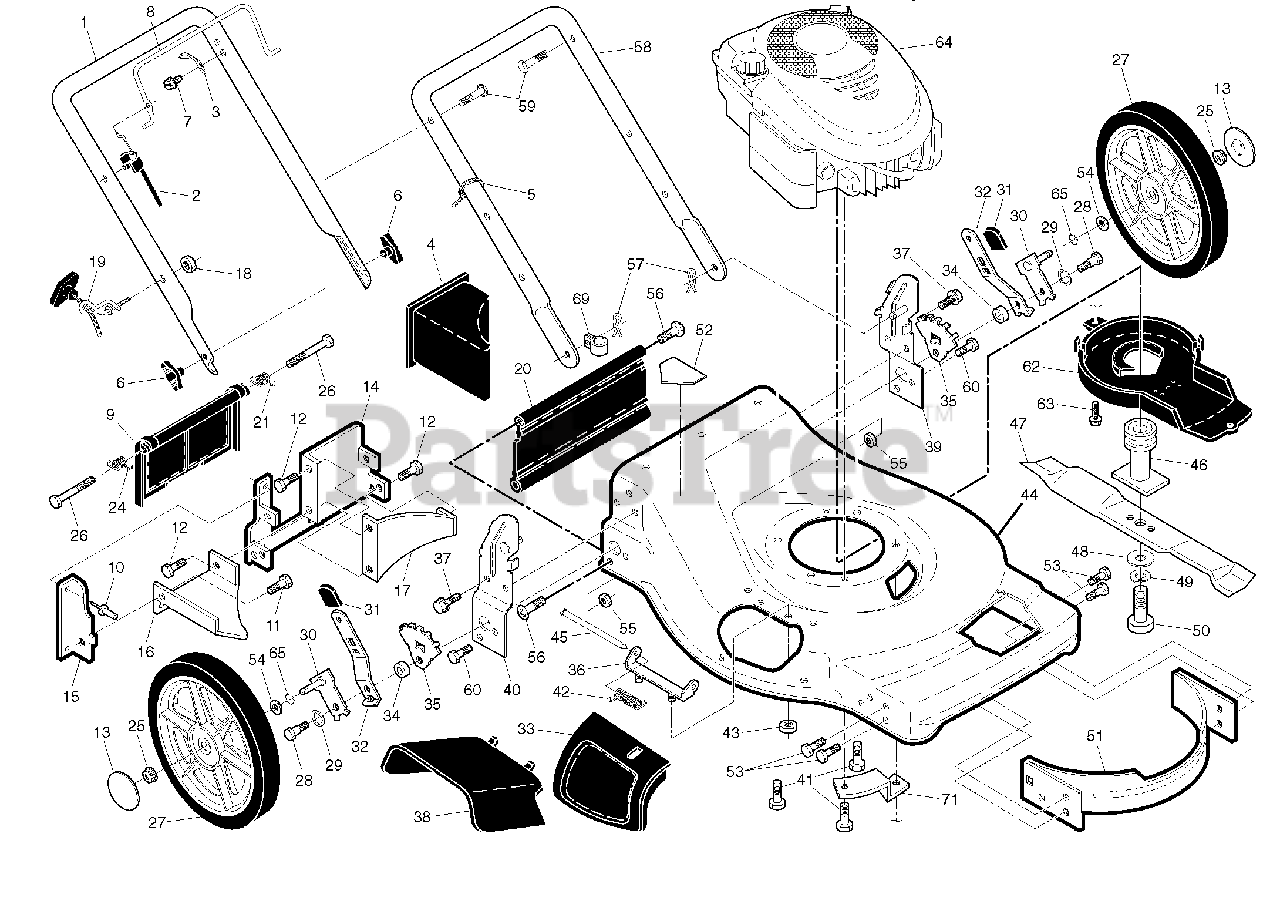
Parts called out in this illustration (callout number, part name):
1	Upper Handle
2	Cable, Operator Presence
3	Bracket, Upstop
4	Mulcher Plug
5	Wire Tie
6	Handle Knob
7	Screw
8	Control Bar
9	Rear Door Assembly
10	Pop Rivet
11	Screw, Self-Tapping #10-24 x 5/8
12	Screw, Hex Hex Head, Sems 1/4-20 x 1/2
13	Hubcap
14	Back Plate
15	Side Baffle
16	Discharge Baffle
17	Rear Baffle
18	Keps Locknut 1/4-20
19	Rope Guide
20	Rear Skirt
21	Spring, Rear Door, LH
24	Spring, Rear Door, RH
25	Nut, Hex, Flanged
26	Bolt, Rear Door
27	Wheel & Tire Assembly, Rear
28	Bolt, Shoulder 3/8-16 x 1
29	Washer, Curved, Cylindrical
30	Axle Arm Assembly
31	Selector Knob
32	Selector Spring
33	Mulcher Door
34	Spacer
35	Wheel Adjusting Bracket
36	Hinge Bracket Assembly
37	Screw, Sems, Thread Cutting 5/16-18 x 3/4
38	Discharge Deflector
39	Handle Bracket Assembly, LH
40	Handle Bracket Assembly, RH
41	Screw, Hex Head, Threaded, Rolled 3/8-16 x 1-1/8
42	Spring, Torsion
43	Nut, Hex, Nylock
44	Kit, Mower Housing
45	Rod, Hinge
46	Blade Adapter / Pulley
47	Blade, 22"
48	Washer, Hardened
49	Washer, Helical
50	Screw, Machine, Hex Head 3/8-24 x 1-3/8 Grade 8
51	Kit, Front Baffle
52	Danger Decal
53	Screw, Serrated, TT 1/4-20
54	Washer, Flat
55	Nut, Hex 3/8-16
56	Hinge Screw 1/4-20 x 1-1/4
57	Hairpin Cotter
58	Lower Handle
59	Handle Bolt
60	Bolt, Hex Head 3/8-16 x 3/4
62	Debris Shield
63	Screw, Debris Shield
65	O-Ring
69	Clip, Cable
71	Mounting Bracket, Debris Shield
71	Operator's Manual, English
71	Operator's Manual, French
71	Repair Parts Manual
